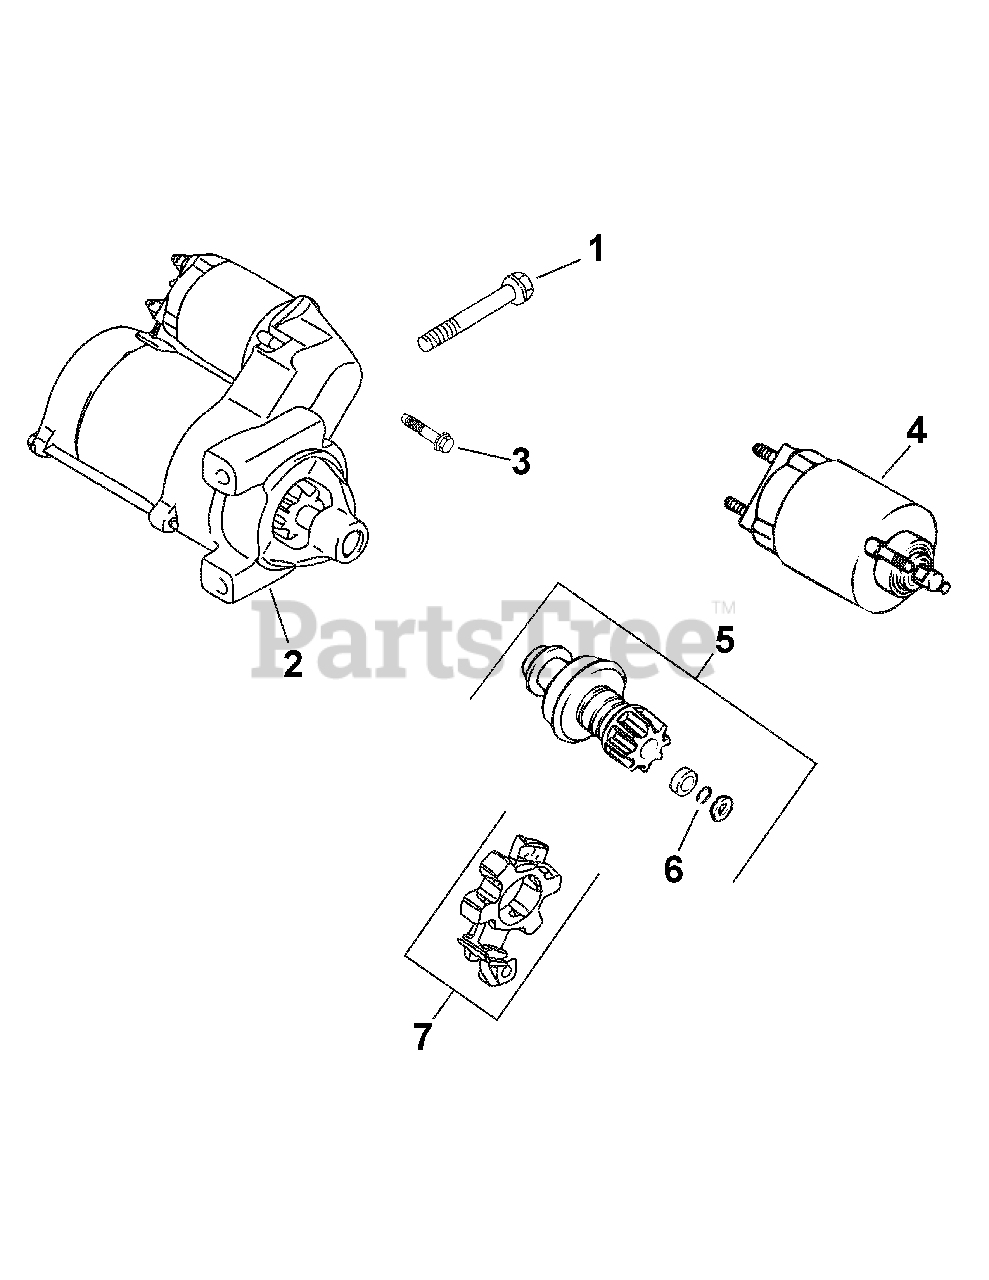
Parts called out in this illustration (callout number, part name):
1	Screw, hex. Flange M8x1.25x80 (2)
2	Starter, solenoid assembly (Includes 3-7)
3	Screw, external torx hd. (3)
4	Kit, solenoid (Includes 3)
5	Kit, starter pinion (Includes 6)
7	Brush, holder
